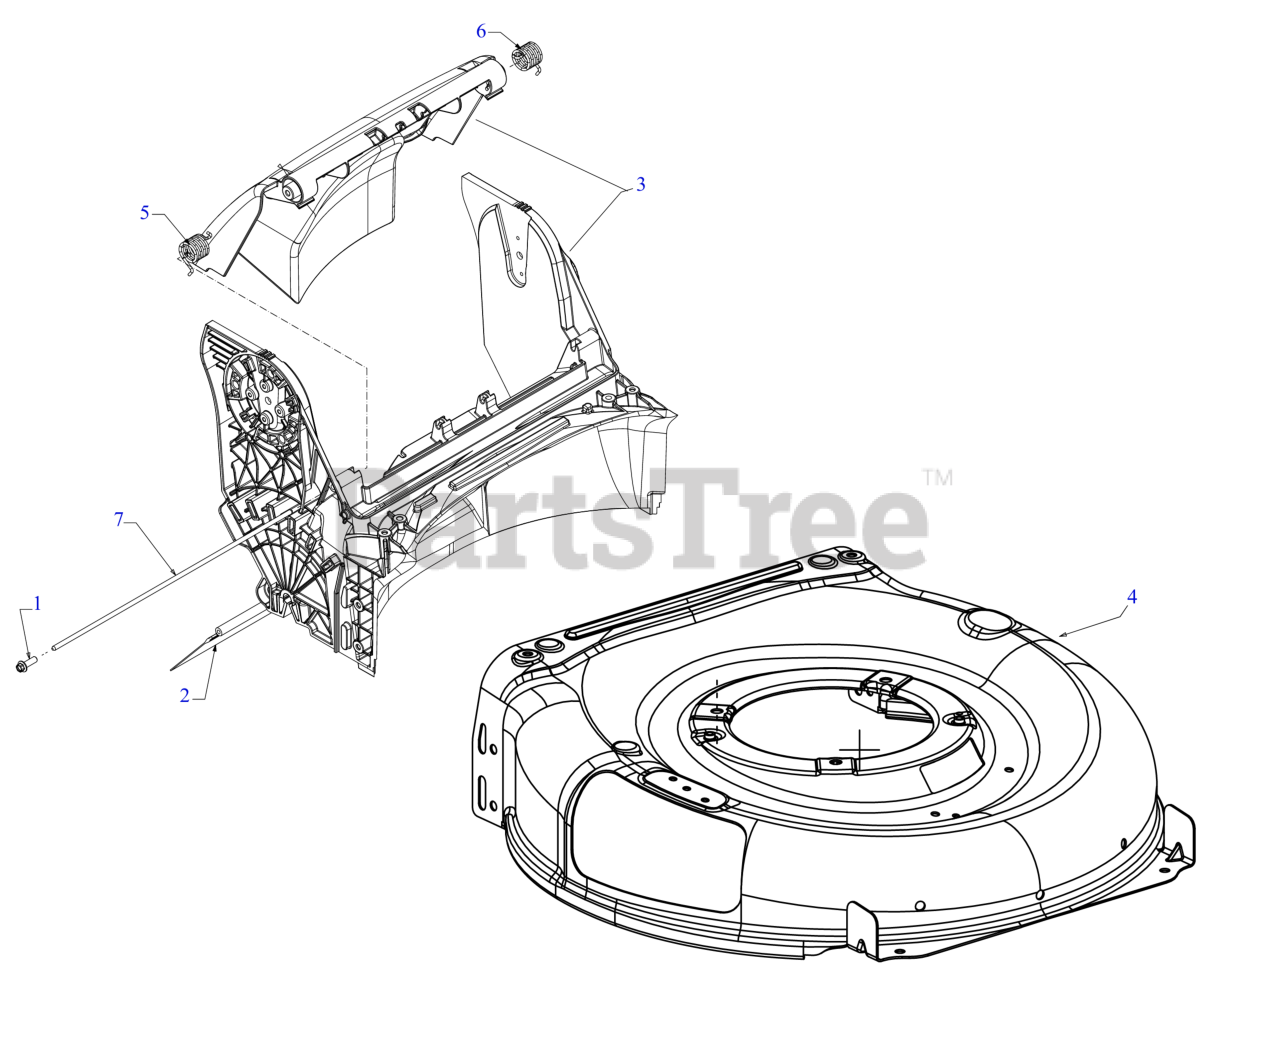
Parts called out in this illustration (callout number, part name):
1	SCREW 1/4 x .750
2	TRAILSHIELD
3	BAFFLE (REAR)
5	TORSION SPRING (RH)
6	TORSION SPRING (LH)
7	REAR DOOR PIVOT ROD
